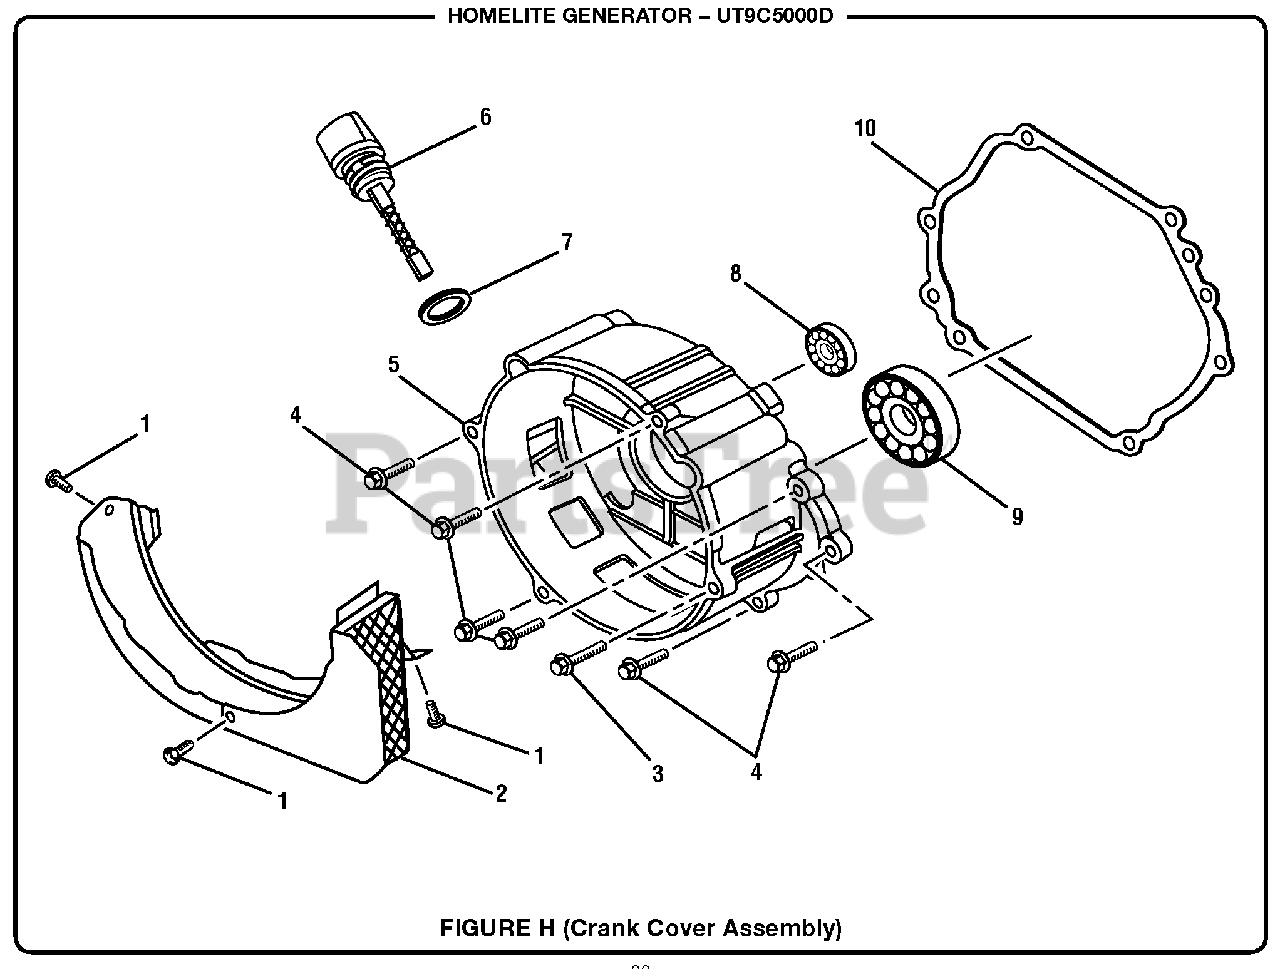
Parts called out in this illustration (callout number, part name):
1	Bolt (M5 x 12 mm, Flange Hd)
2	Guard Cover (Crankcase)
3	Bolt (M8 X 40 mm)
4	Bolt (M8 X 35 mm)
5	Crankcase Cover Assembly
6	Dipstick Assembly
7	Gasket (Dipstick)
8	Ball Bearing (6202)
9	Ball Bearing 6207
10	Gasket (Crankcase)
